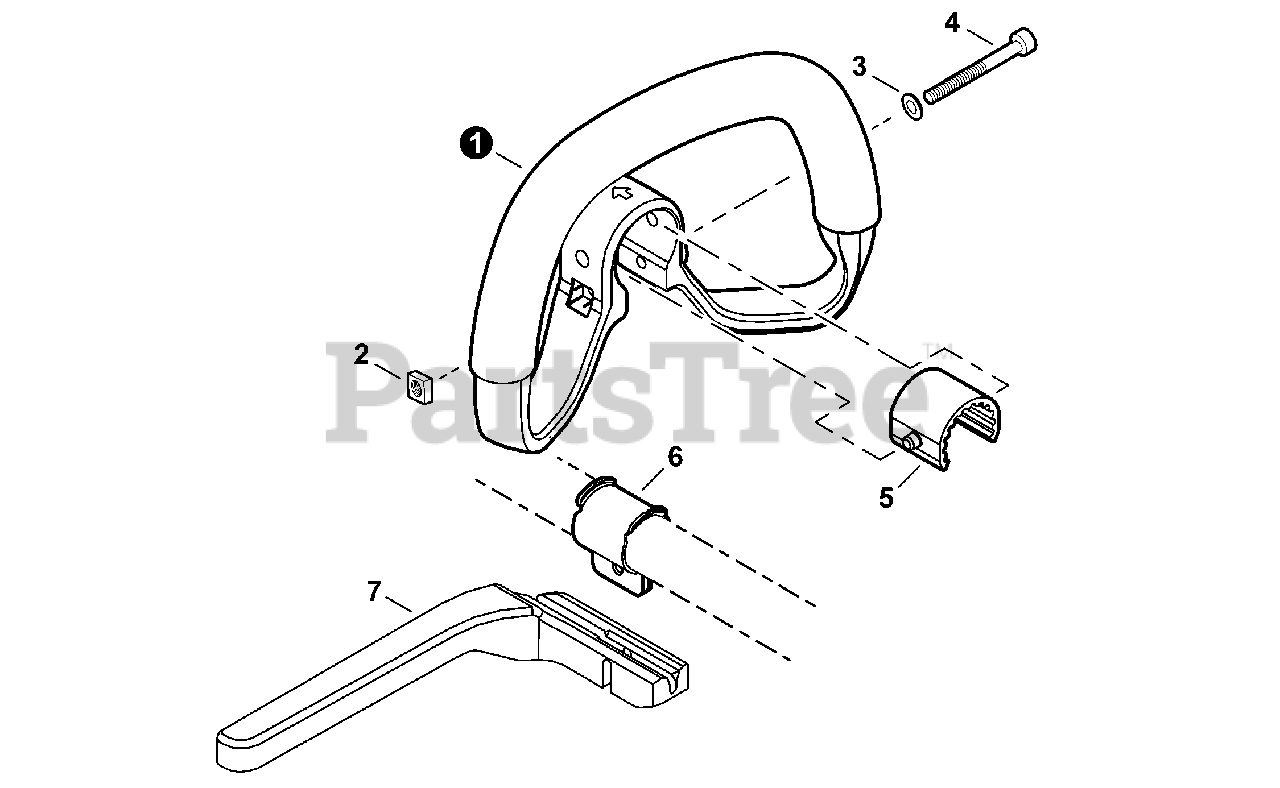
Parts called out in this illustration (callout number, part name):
1	HANDLE, SUPPORT
3	WASHER 5.5×12×0.8
4	BOLT, TORX 5×40
5	CUSHION
6	BRACKET, MOUNTING
7	BAR, BARRIER
